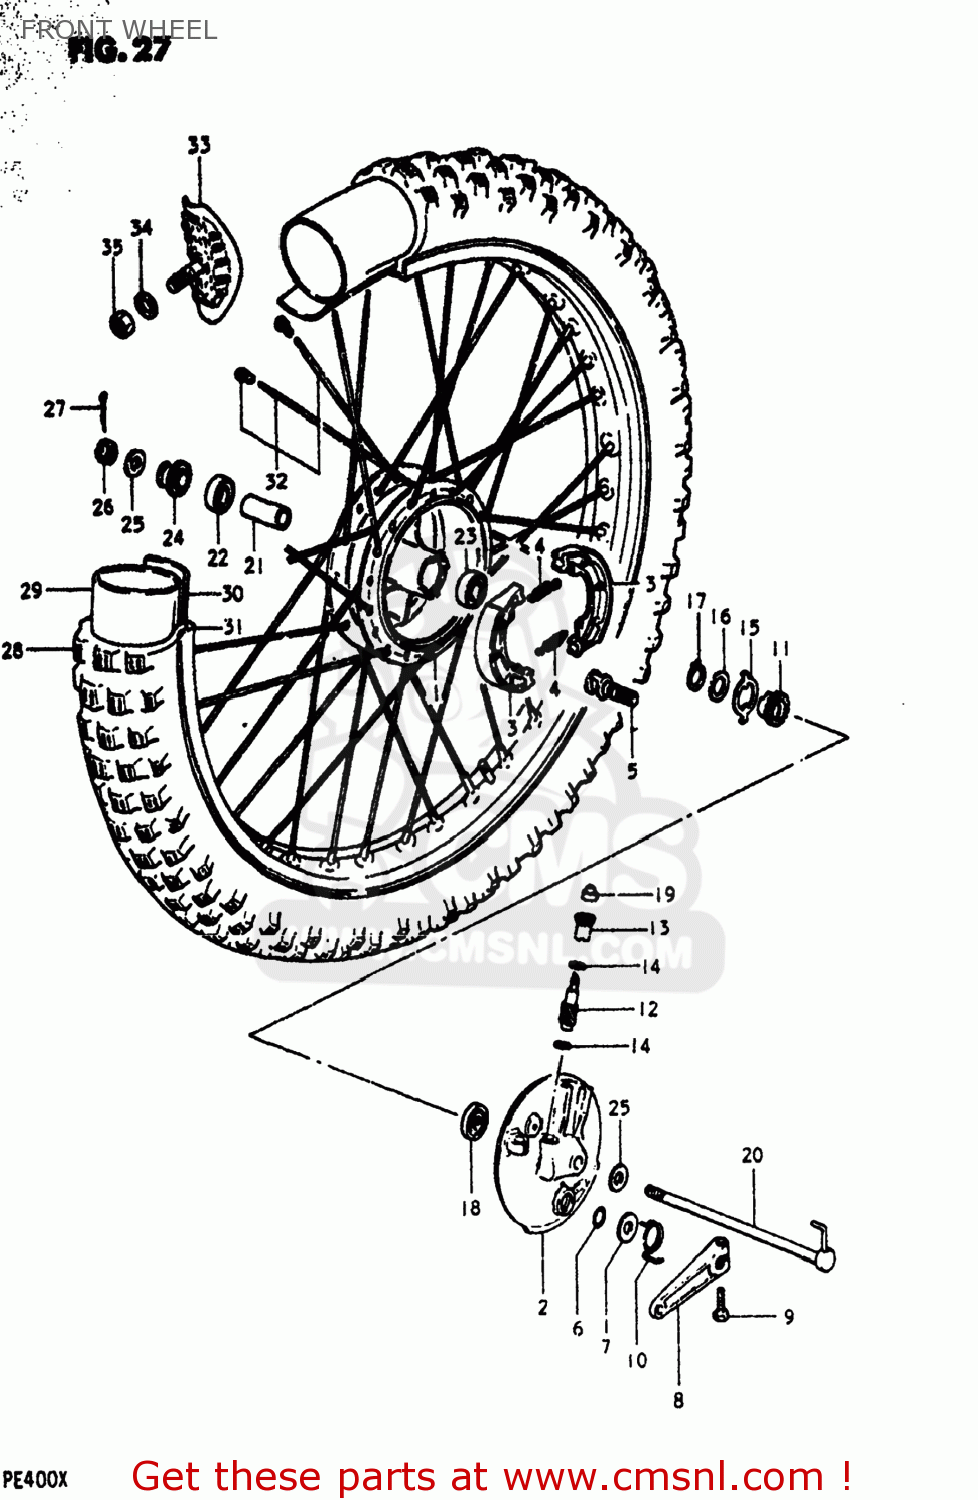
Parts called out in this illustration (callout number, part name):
1	DRUM,FRONT HUB
2	PANEL,FRONT HUB
3	SHOE,BRAKE
4	SPRING
5	CAM,FRONT BRAKE
6	O-RING,BOSS
7	WASHER (15X24X1.6)
8	LEVER,FRONT BRAKE CAM
9	BOLT
10	SPRING
11	GEAR,SPEEDOMETER
12	PINION,SPEEDOMETER
13	BUSHING,SPEEDOMETER PINION
14	WASHER (5.1X9X0.4)
15	DRIVER,SPEEDOMETER GEAR
16	WASHER(22.5X27X1)
17	CIRCLIP
18	SEAL,OIL(26X38X4)
19	SEAL,OIL(6X10X3)
20	AXLE,FRONT
21	SPACER (12.6X19X52)
22	BEARING, RH
23	BEARING
24	SPACER,FRONT AXLE,RIGHT
25	WASHER
26	NUT, REAR AXLE
27	COTTER PIN
28	TIRE,FRONT
29	TUBE,INNER
30	PROTECTOR,WHEEL,INNER
31	RIM,FRONT WHEEL
32	SPOKE SET,FRONT
33	STOPPER,BEAD
34	WASHER
35	NUT
